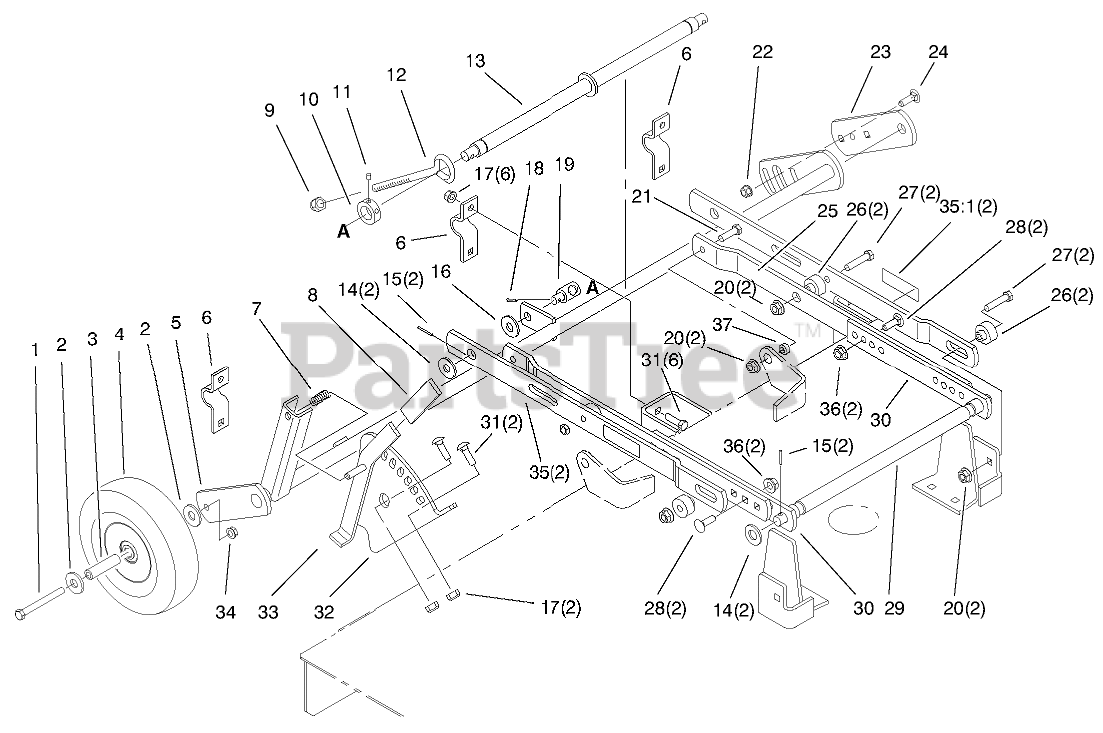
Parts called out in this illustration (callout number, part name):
1	SCREW-HH
2	WASHER-FLAT
3	SPACER
4	ASSY-GAUGE WHEEL
5	WHEEL SUPPORT
6	Clamp
7	SPRING-COMPRESSION
9	NUT-LOCK, NI
10	COLLAR
11	SCREW-SET, HSH
12	ROD-ADJUSTMENT, LEVEL
13	SHAFT-LEVELER
14	WASHER-FLAT
15	PIN-ROLL, SPIROL
16	WASHER-FLAT
17	NUT-LOCK, NI
18	PIN-COTTER
19	TRUNNION
20	LOCKNUT-FLANGE
21	SCREW-HH
22	NUT-FLANGE
23	SUPPORT-GAGE WHEEL
24	BOLT-CARR
25	DRAFTBAR
26	SPACER
27	SCREW-HH
28	SCREW-CARR
29	Shaft-Draftbar
30	DRAFTBAR-ADJUSTMENT
31	BOLT-CARR
32	QUADRANT-DECK
33	HOC Lever
34	NUT-HEX
35	Leveler ASM LH (Only On: 78395)
35	Leveler ASM LH (Only On: 78469)
35	Leveler ASM RH (Only On: 78395)
35	Leveler ASM RH (Only On: 78469)
35:1	Decal-Warning (Only On: 78395)
35:1	Decal-Warning (Only On: 78469)
36	NUT-LOCK, CONE
37	SPACER
